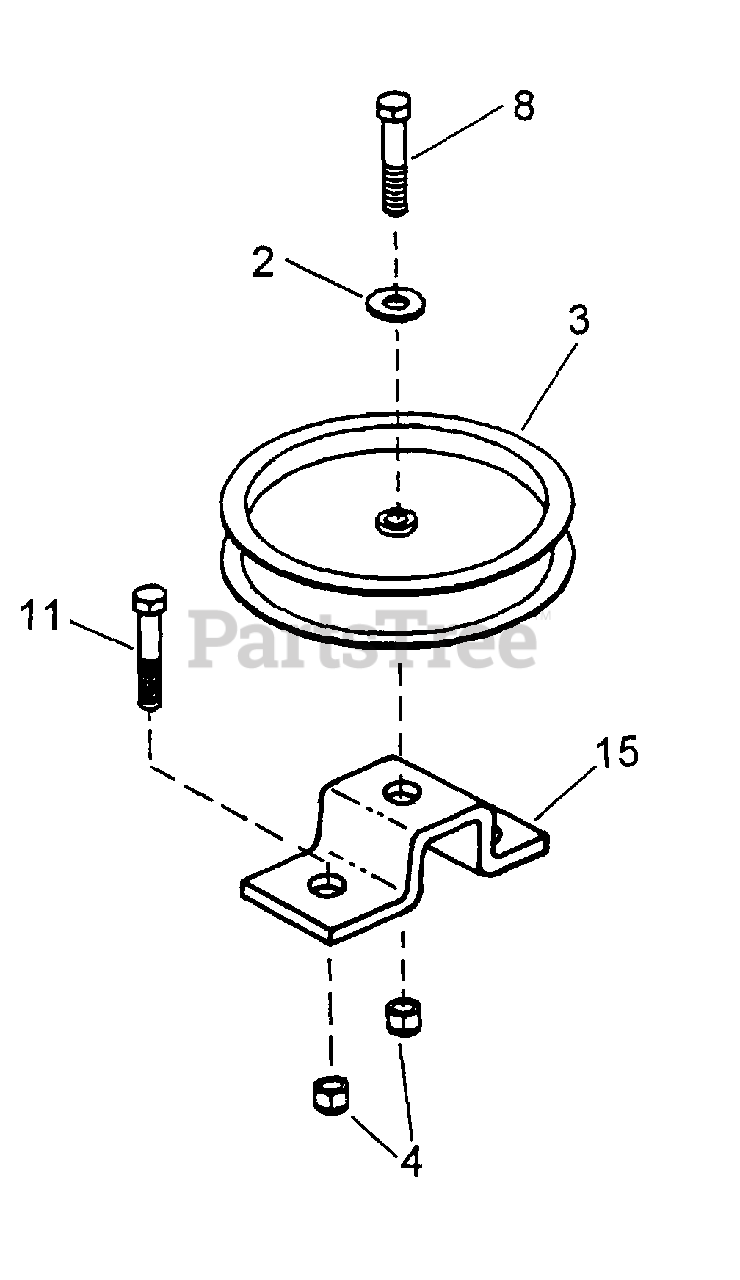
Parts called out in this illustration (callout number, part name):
2	WASHER, 3/8" USS
3	PULLEY, Idler 5-1/2" O.D.
4	NUT, 3/8-16 HEX NYLON LOCK
8	SCREW, 3/8-16 x 1-3/4" Hex Head Cap, Grade 5
11	BOLT, 3/8-16 X 1" GD5 CZ
15	STAND, Fixed Idler
